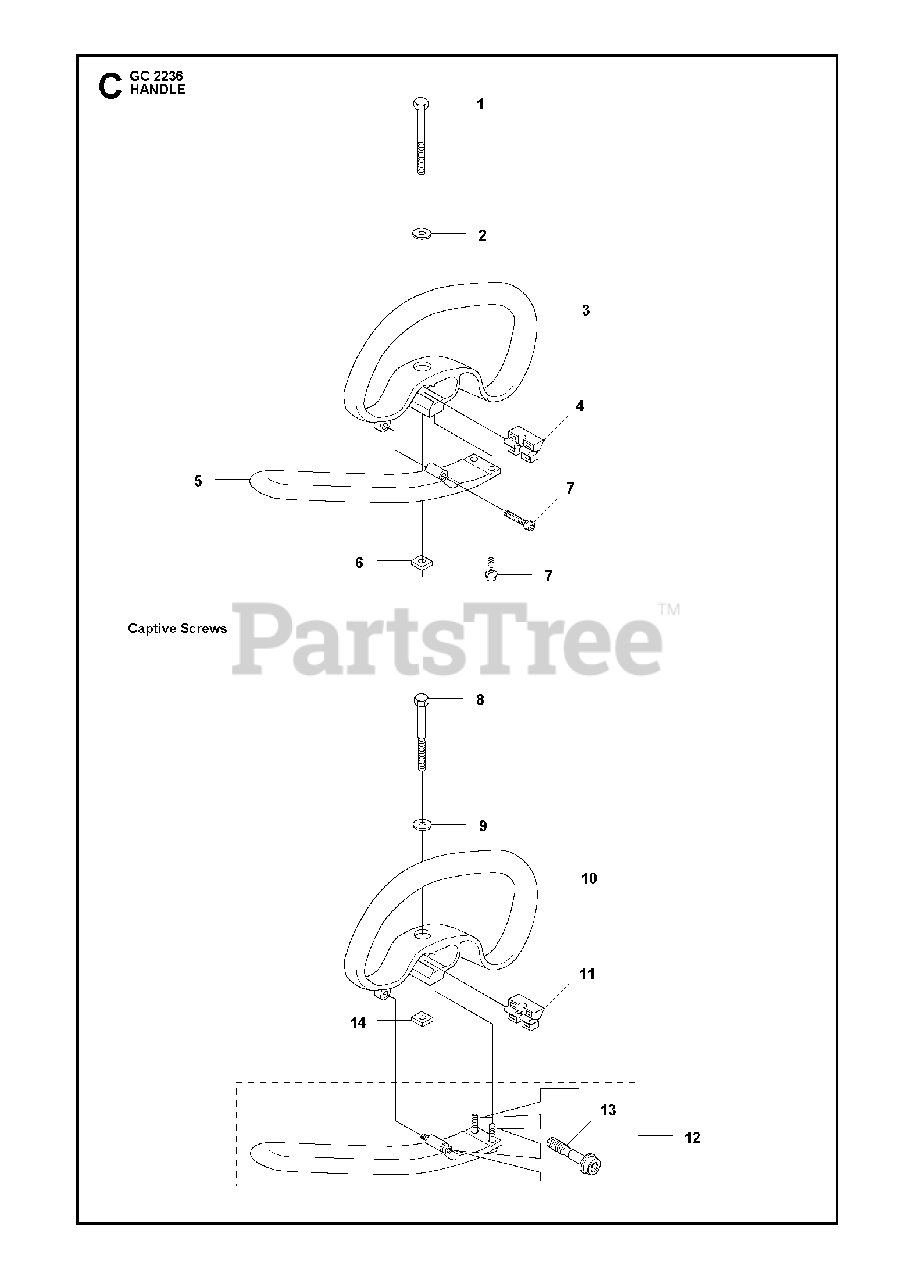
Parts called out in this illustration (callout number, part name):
4	SPACING BLOCK
7	SCREW
10	HANDLE.LOOP
11	SPACING BLOCK
12	HANDLE
13	SCREW IHSCFTO
